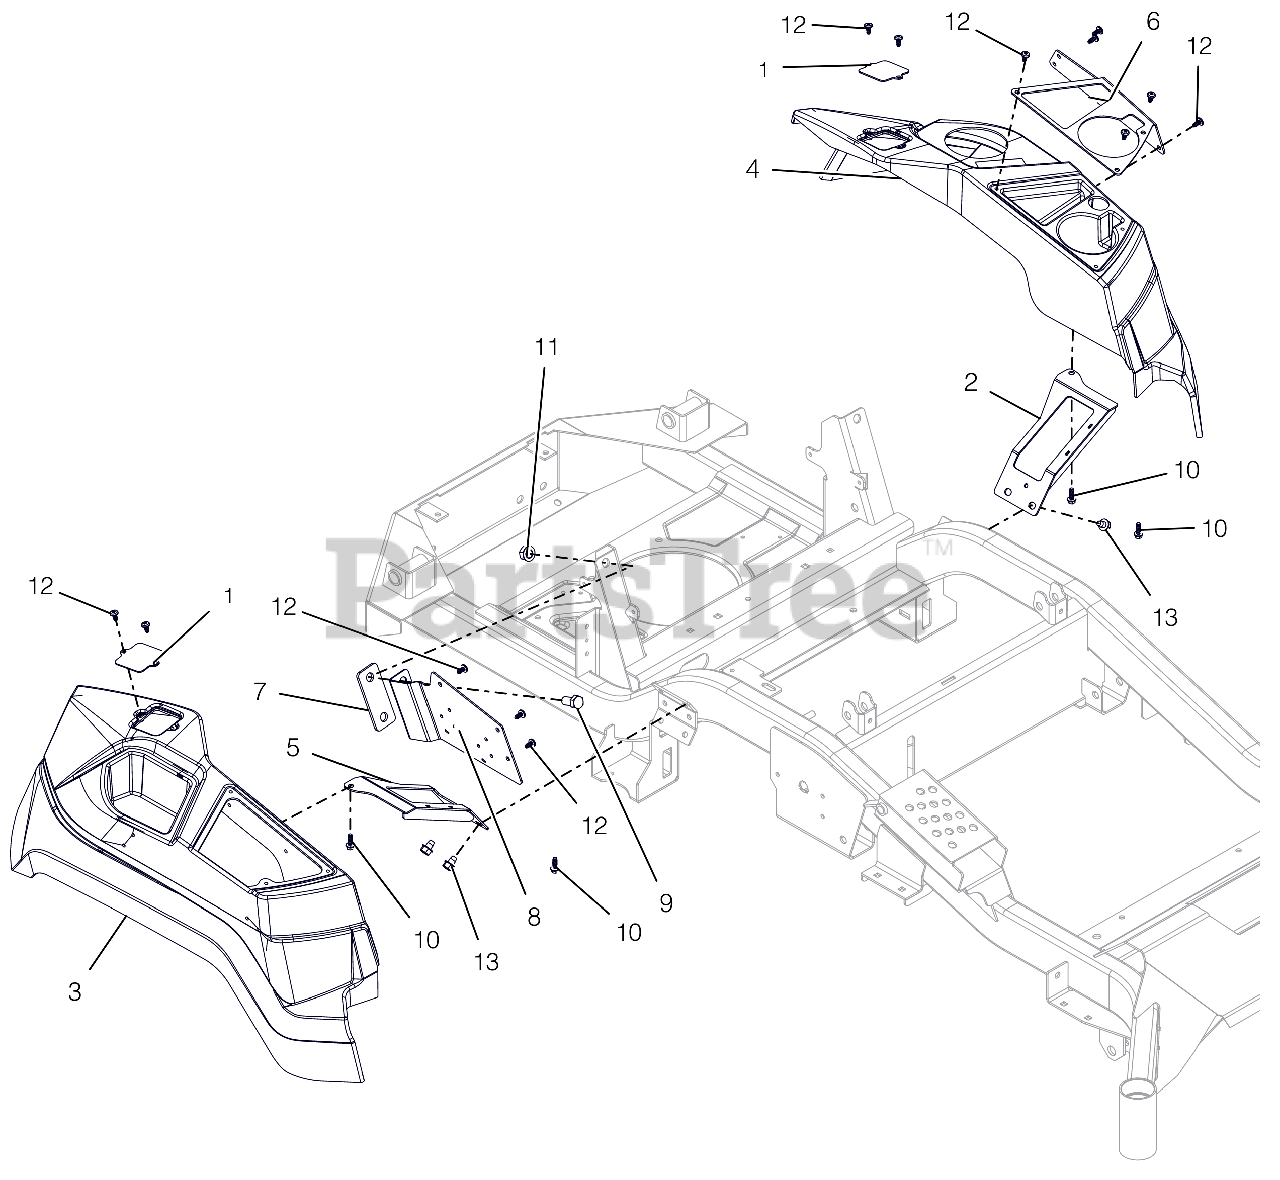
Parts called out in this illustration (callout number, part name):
1	PLATE, ROPS HOLE-HD
2	WLDMT, LH FENDER MOUNT
3	FENDER, RH APEX - 2017
4	FENDER, LH APEX - 2017
5	WLDMT, RH FENDER MOUNT
6	PLATE, APEX CUP HOLDER COVER
7	PLATE, CONTROL PANEL SPACER
8	BRKT, FENDER/RELAY MOUNTING
9	@BLT-HEX .50-13X1.00 GR5 YWZC
10	SCR-PLASTITE .25-10X.75, YWZC
11	@NUT-LK-TOP-FLG .50-13 YWZC
12	SCR-PAN .25-15X.50 6L H/LZB500
13	@SCR-TAP .38-16X.50 HWH TR YWZ
